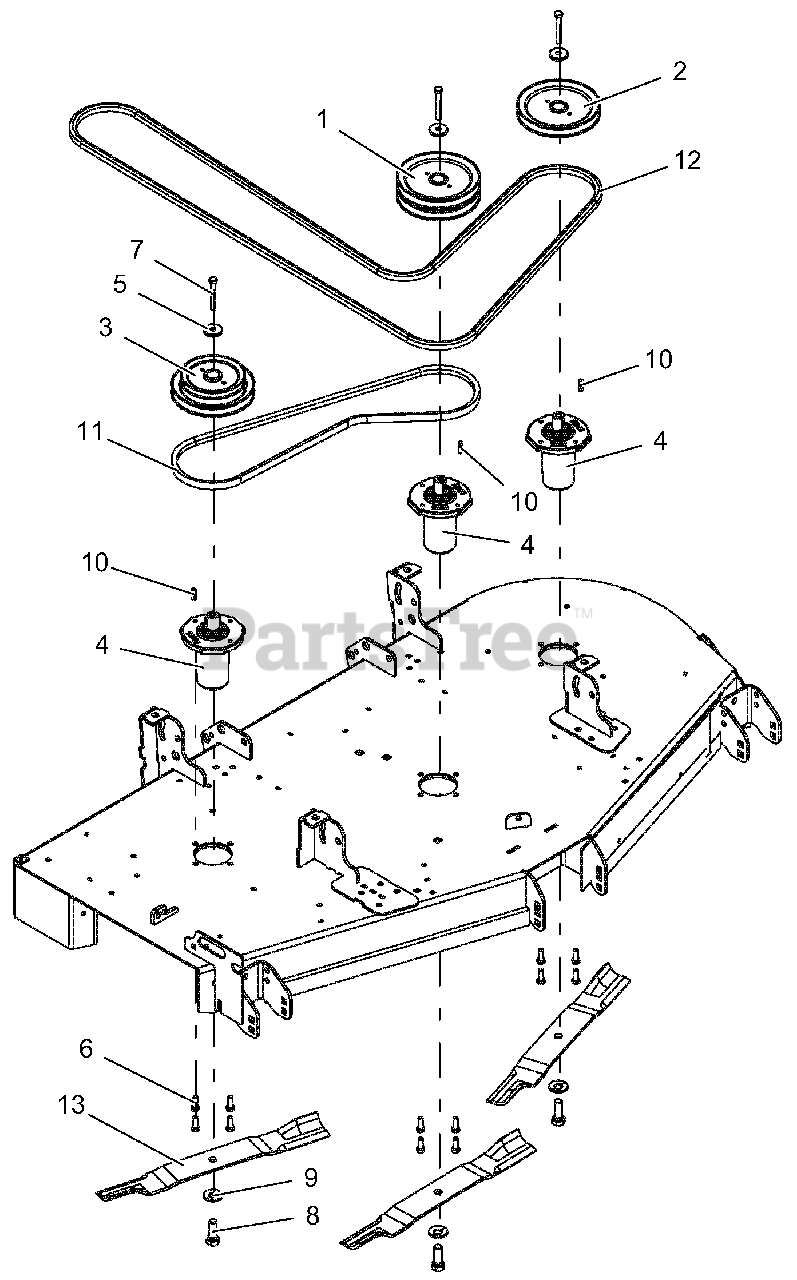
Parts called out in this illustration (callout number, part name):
1	PULLEY, DOUBLE 1"ID X 6.75"OD-BLACK
2	PULLEY, V-1" ID X 6.75" OD-BLACK
3	PULLEY, DOUBLE -1" ID X 6.75" & 5.25" OD
4	SERVICE, ASM SPINDLE- DUCTILE
5	RETAINER, SHEAVE SPINDLE
6	BLT-HEX .38-16X1.00 GR5 YWZC EP30
7	BLT-HEX .38-16X2.75 GR8 YWZC
8	BLT, HEX .62-18X1.75 GR8 YWZC
9	WSHR, BLVL .63X1.625X.14
10	KEY-SQ .250X.250X1.00 RC 40-50
11	BELT, B 63.00 RAW COGGED
12	BELT, BB 118.00 WRAPPED HEX
13	BLADE, MOWER 60"
